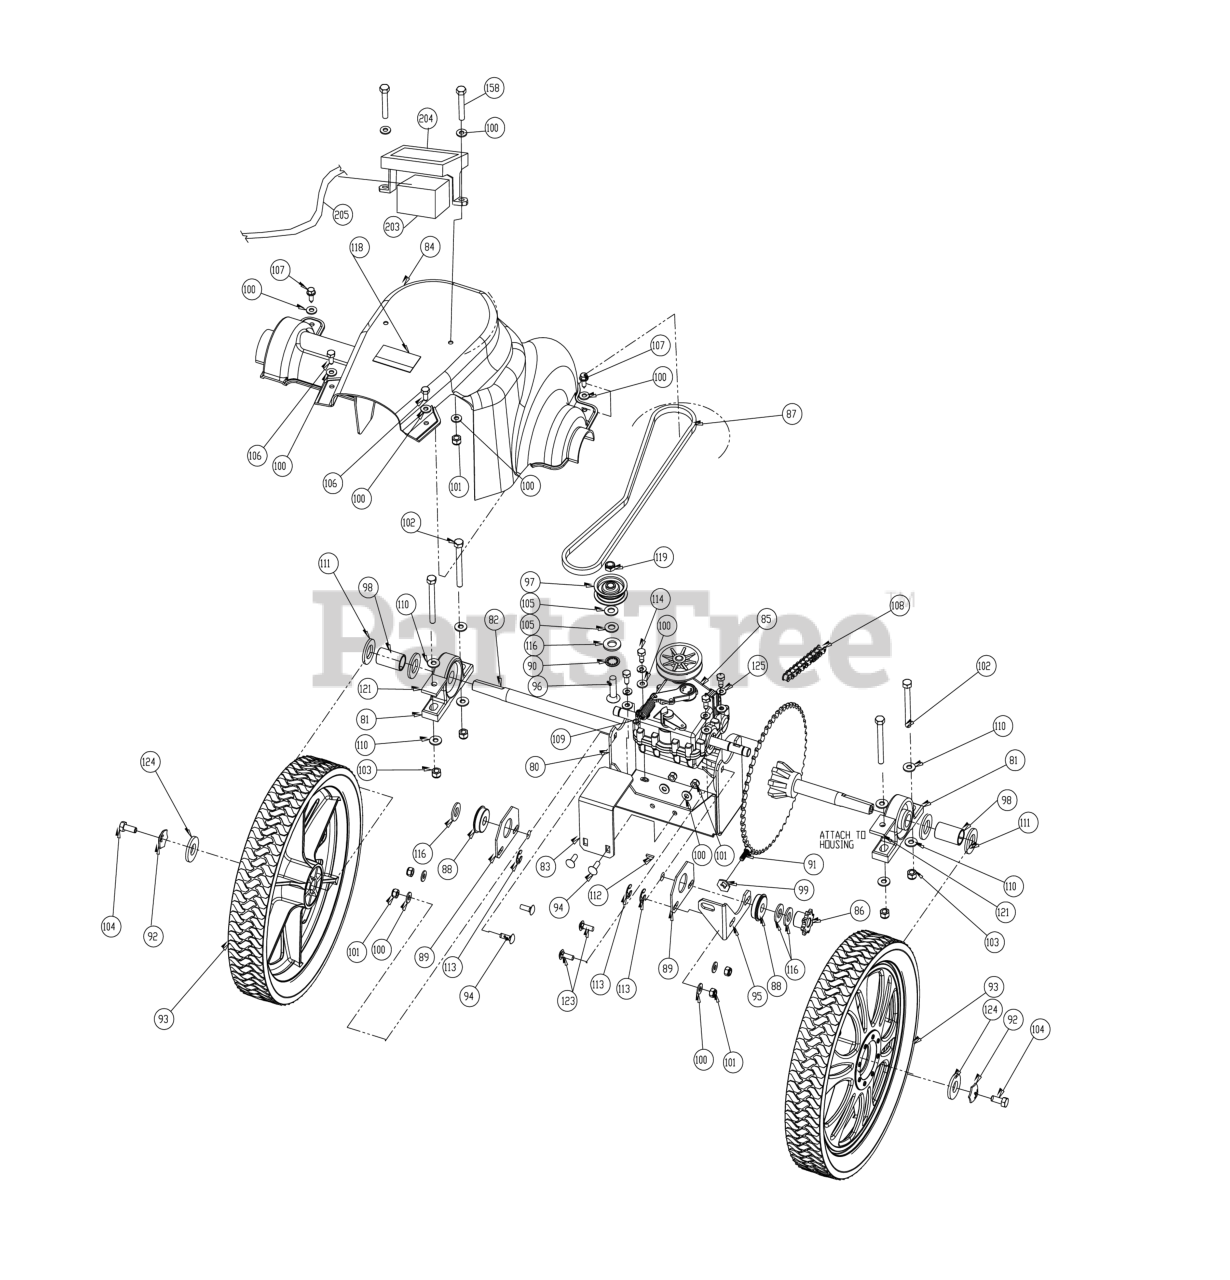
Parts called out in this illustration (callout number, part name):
80	BRACKET TRANS MOUNT WA VAC
81	BEARING 3/4" CAST P BLOCK
82	DIFFERENTIAL 54 TOOTH D CUT
83	BRACKET TRANS ANTI ROTATE
84	GUARD COVER TRANS DRIVE
85	TRANSMISSION 3 SP GENERAL TRANS
86	SPROCKET 8 TOOTH 41B8
88	BEARING 1/2" CLIP
89	PLATE TRANS BEARING SUPPORT
90	WASHER LOCK 1/2" INTERNAL TOOTH
91	SCREWCAP 1/4"-20X3/4" HCS ZP
92	WASHER LOCK 5/16" TWISTED TOOTH HEAVY
93	WHEEL AND TIRE 14" TREADED
94	BOLT CARRIAGE 1/4" X 3/4"
95	BRACKET TRANS REINFORCE VAC
96	BOLT CARRIAGE 3/8"-16 X 1 1/2" ZP
97	PULLEY IDLER 2"OD X 3/8" ID
98	SPACER WHEEL 0.75 ID
99	BRACKET BEARING FIX MV
100	WASHER 1/4"SAE9/32"X5/8"X1/16"
101	NUT LOCK 1/4"-20 HEX Z/P
102	SCREWCAP 5/16"-18 X 3" HCS ZP
103	NUT LOCK 5/16"-18 HEX Z/P
104	SCREWCAP 5/16"-18X3/4" HCS ZP
105	WASHER 3/8"SAE 13/32"X13/16"X1/16"
106	SCREW SELF TAP 1/4"-20 X 5/8" HWH TYPE F
107	SCREW SM 1/4"X3/4" TYPE A HX WF
108	SEE: 840072-S
109	SPRING EXTENSION
110	WASHER 1/4" FLAT Z/P
111	WASHER 3/4" SAE 13/16"X1.5"X1/8"ZP
112	KEY WOODRUFF 1/8" X 1/2"
113	RING RETAINING 1/2"
114	SCREWCAP 1/4"-20 X 5/8" GR 5
116	WASHER 1/2"FC9/16"X1 3/8"X7/64"
118	LABEL DANGER
119	NUT LOCK 3/8-16 LT WT THIN ZP
121	BRACKET BEARING FIX MV
123	BOLT CARRIAGE 1/4"-20 X 1" ZP
124	WASHER FLAT FENDER 5/16
125	WASHER LOCK 1/4" S/T MED
195	BEARING 1/2 ID
